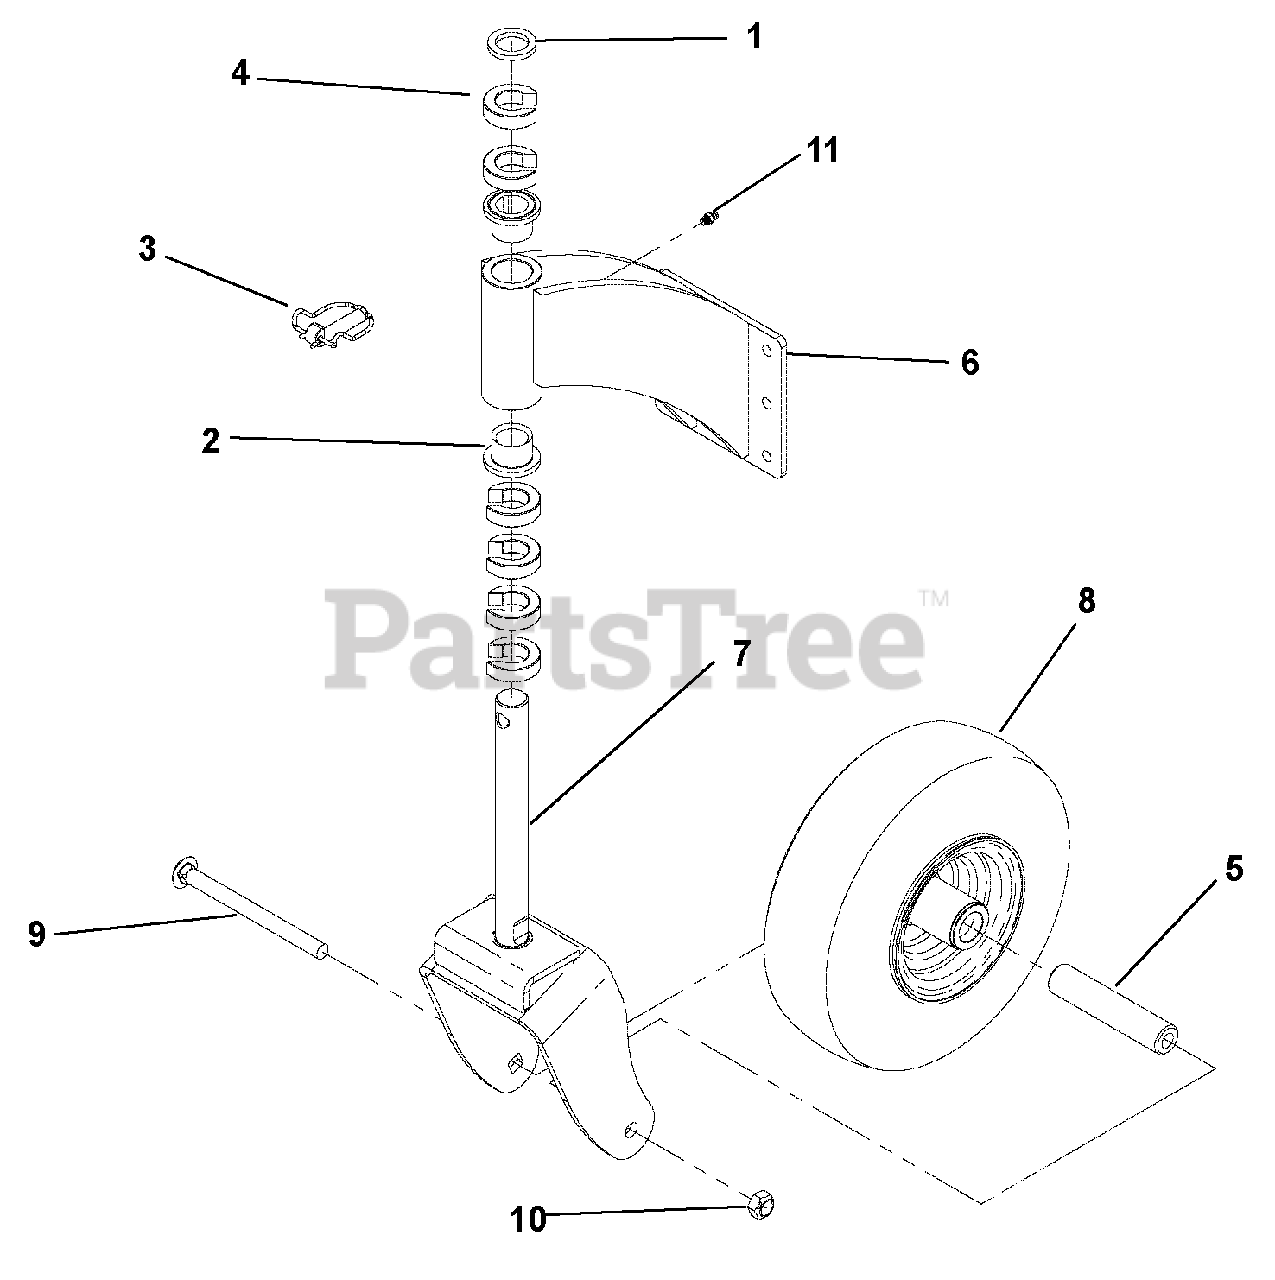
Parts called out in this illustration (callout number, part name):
1	BUSHING, 1.03X1.501.179
2	BRG, FLG 1.00X1.25X1.00
3	PIN, LOCK .438 X 2.00
4	C-SPACER, 1.00X1.77X.50
5	TUBE, 1.00X.50X4.76
6	WLDMT, CASTER MOUNT BRKT
7	WLDMT, FRONT WHEEL FORK
8	WHEEL, FRONT 11X4X5
9	BLT-HEX .50-13X6.00 GR5 YWZC
10	@NUT-LK-CTR .50-13 YWZC
11	GREASE ZERK, 1/4-28 STR .69 LG
